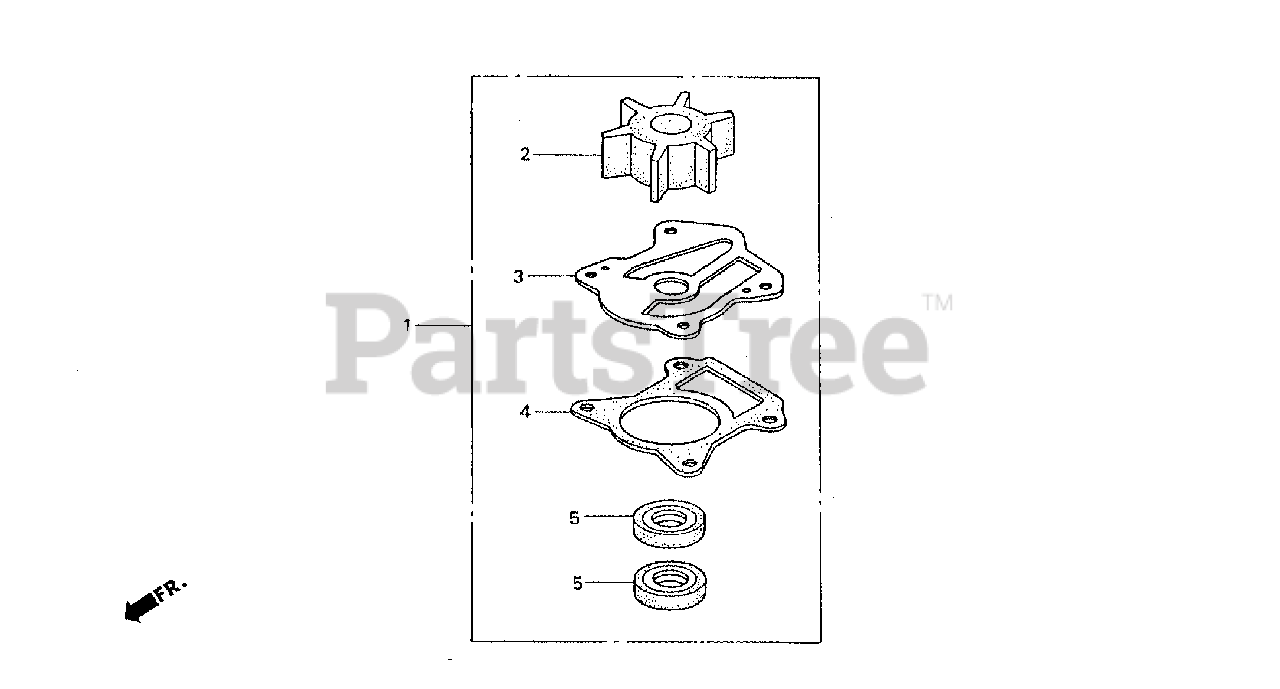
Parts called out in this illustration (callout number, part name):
1	IMPELLER KIT, WATER PUMP
2	IMPELLER, PUMP
3	GASKET B, IMPELLER
4	GASKET, WATER PUMP
5	SEAL, WATER (17X30X7)
